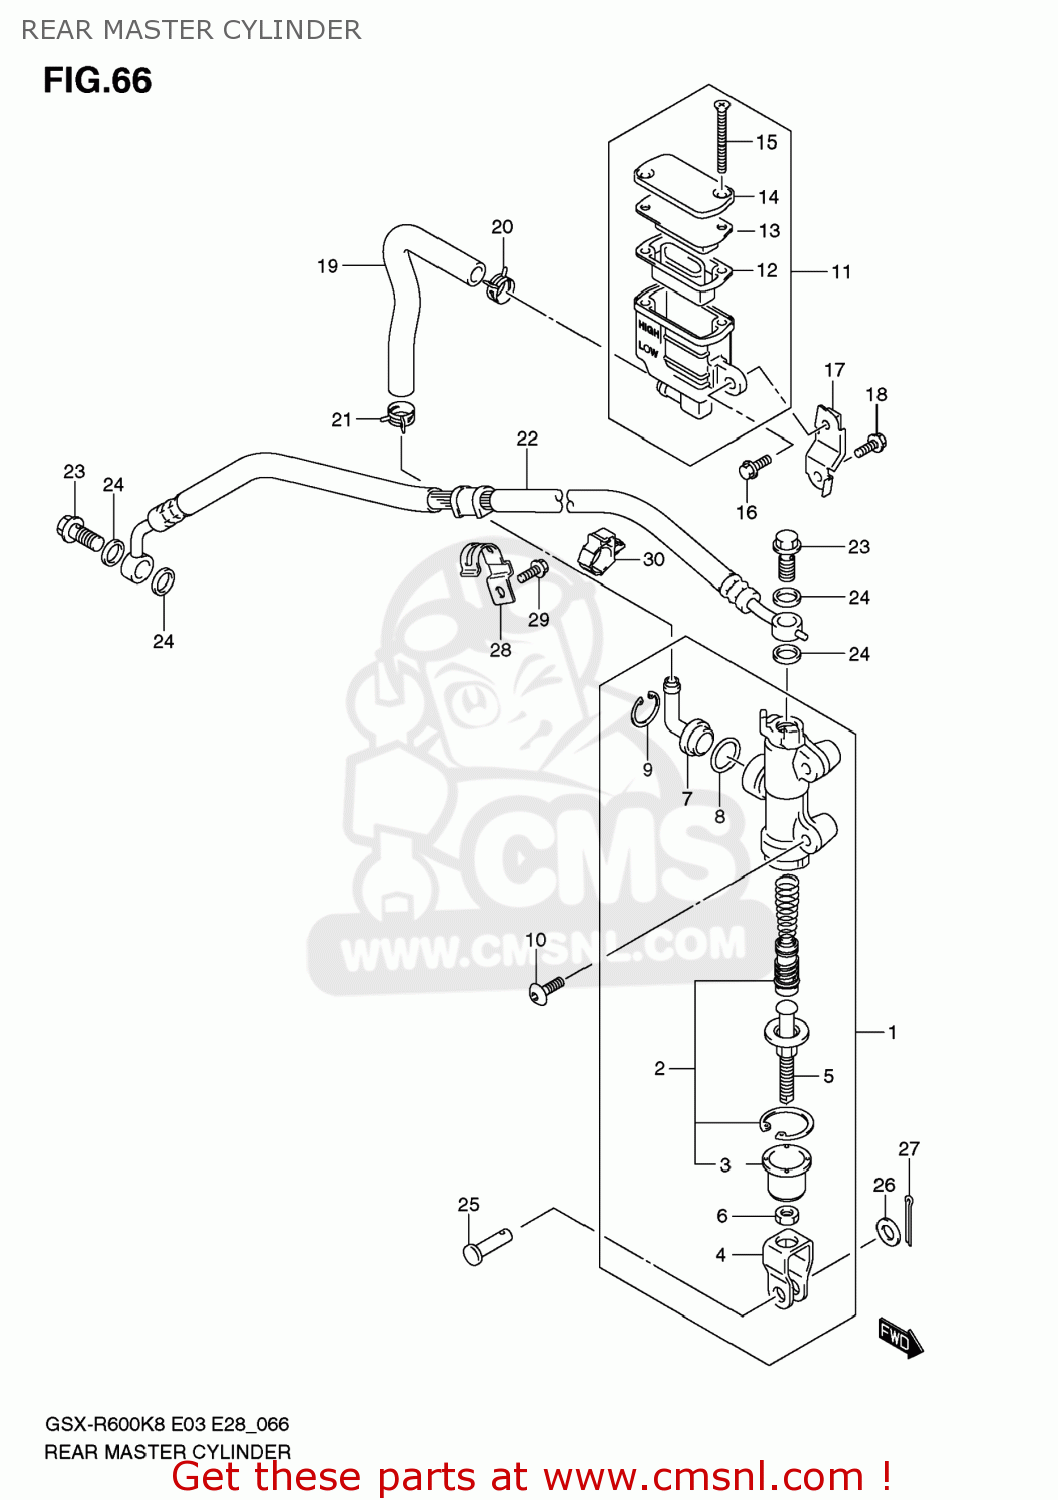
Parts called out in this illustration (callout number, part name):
1	CYLINDER ASSY,RR MASTER
2	PISTON/CUP SET
3	BOOT
4	YOKE
5	ROD,PUSH
6	NUT
7	CONNECTOR
8	O RING
9	CIRCLIP
10	SCREW(6X20)
11	TANK ASSY,RESERVOIR
12	DIAPHRAGM
13	PLATE,DIAPHRAGM
14	CAP
15	SCREW
16	BOLT
17	BRACKET,RR RESERVOIR TANK
18	BOLT
19	HOSE,RR RESERVOIR TANK
20	CLIP
21	CLIP
22	HOSE,RR BRAKE
23	BOLT UNION
24	WASHER(10X15X1.5)
25	PIN(6X18.2)
26	WASHER
27	PIN
28	CLAMP,RR BRAKE HOSE
29	BOLT
30	CLAMP
